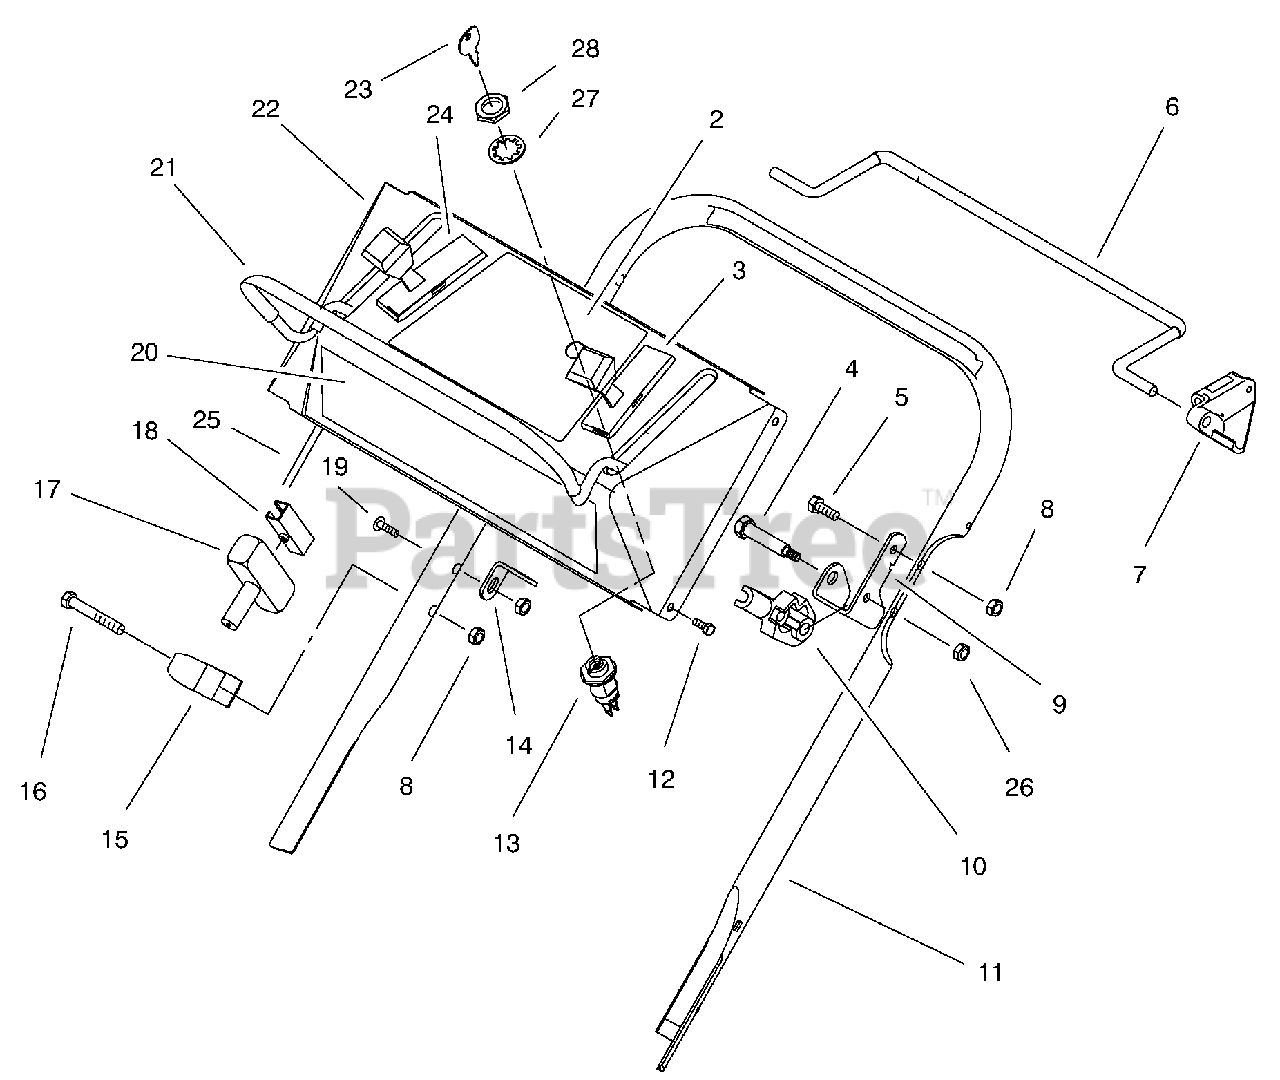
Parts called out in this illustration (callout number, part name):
2	Decal-Warning
3	Cable-Throttle
5	Screw-Hex Hd. Cap
6	Bail-Control S.P.
7	Stop-Pivot
8	Nut-Lock
9	Bail-Stop Bracket
10	Cam-Brake
11	Handle-Upper
12	Screw-Phillips Hd.
13	Switch-Starter
14	Bracket-Cable Anchor
15	Guide-Rope
16	Screw-Hex Hd. Cap
17	Handle-Starter
18	Clip-Rope Insert
19	Screw-Handle
20	Decal-Console Front
21	Bail-Engine Control
22	Panel-Control (Incl. Ref. #2, & 20)
24	Control-Ground Speed
25	Cable-Control
26	Nut-Lock
27	Washer-Star
